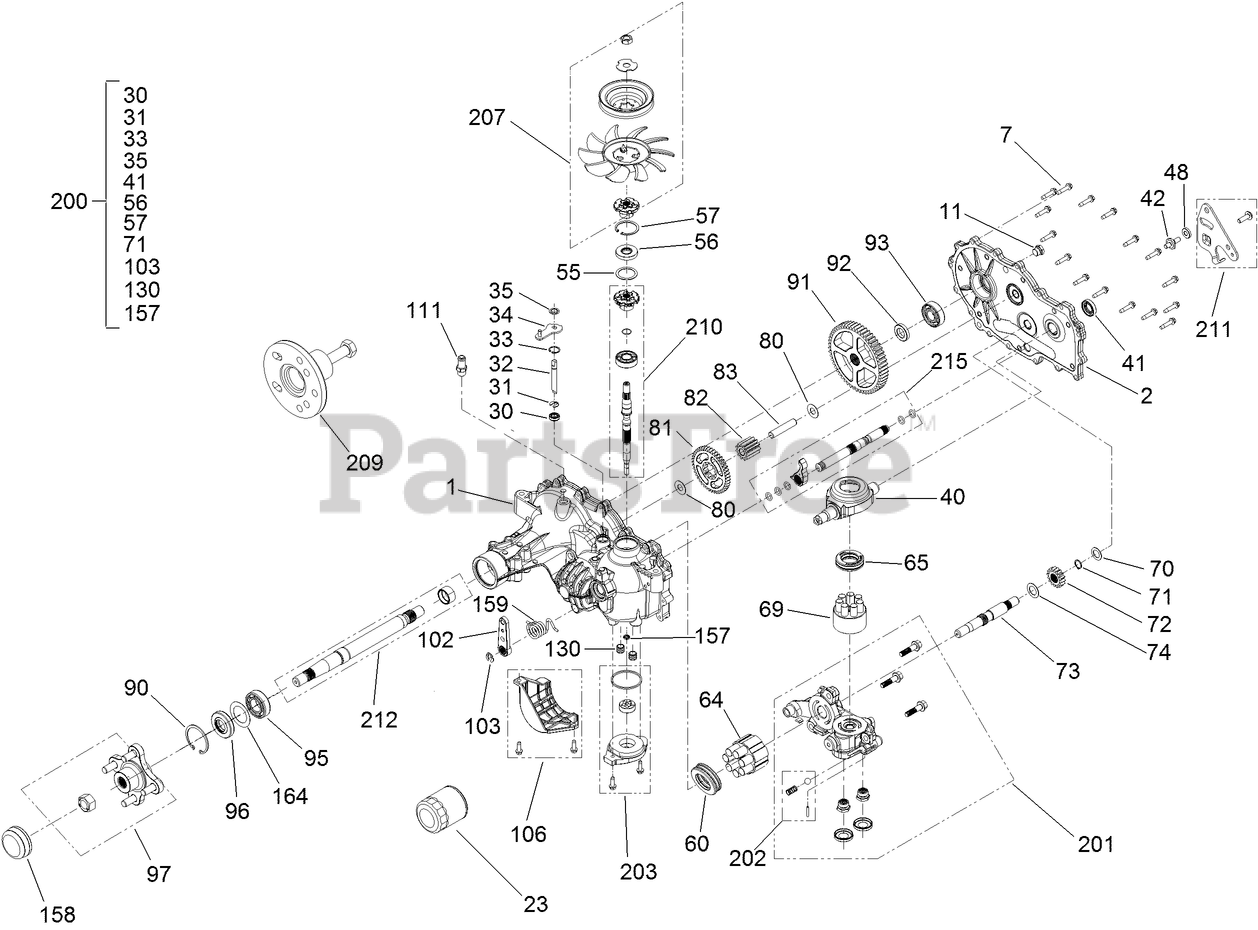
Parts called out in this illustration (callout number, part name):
1	KIT, MAIN HOUSING RH, CHARGE
2	KIT, SIDE COVER RH, CONTROL
7	SCREW-HHF
23	ELEMENT-OIL FILTER, HYD
30	SEAL-LIP
31	RING-RETAINING, EXTERNAL
32	ROD-BYPASS
33	RING-RETAINING, INTERNAL
34	ARM-BYPASS
35	RING-RETAINING, EXTERNAL
40	SWASHPLATE-TRUNNION
41	SEAL-LIP
48	SPACER
55	SPACER
56	SEAL-LIP
57	RING-RETAINING
60	BEARING-THRUST
64	CYLINDER BLOCK ASM KIT
65	BEARING-THRUST
69	PUMP BLOCK ASM
70	WASHER-FLAT
71	RING-RETAINING
72	GEAR-16T
73	SHAFT-MOTOR
74	WASHER
80	WASHER
81	GEAR-43T
82	GEAR-11T
83	PIN-JACKSHAFT
90	RING-RETAINING
91	GEAR-54T
92	SPACER
93	BEARING-BALL
95	BEARING-BALL
97	HUB KIT
102	HANDLE-BRAKE
103	RING-RETAINING, EXT
106	GUARD-FILTER, RH
111	ADAPTER-STRAIGHT
130	TUBE-CHARGE
157	COVER-NUT, AXLE
158	GEROTOR SEAL KIT
159	SPRING, TORSION CCW
164	SPACER
200	SEAL KIT
201	RH CHARGE CENTER SECTION KIT
202	CHARGE RELIEF KIT
203	CHARGE KIT
207	FAN AND PULLEY KIT
209	HUB PULLER KIT
210	INPUT SHAFT KIT
211	KIT, CONTROL ARM
212	AXLE SHAFT KIT
215	KIT, OUTBOARD, RH ROT A / LH ROT B
